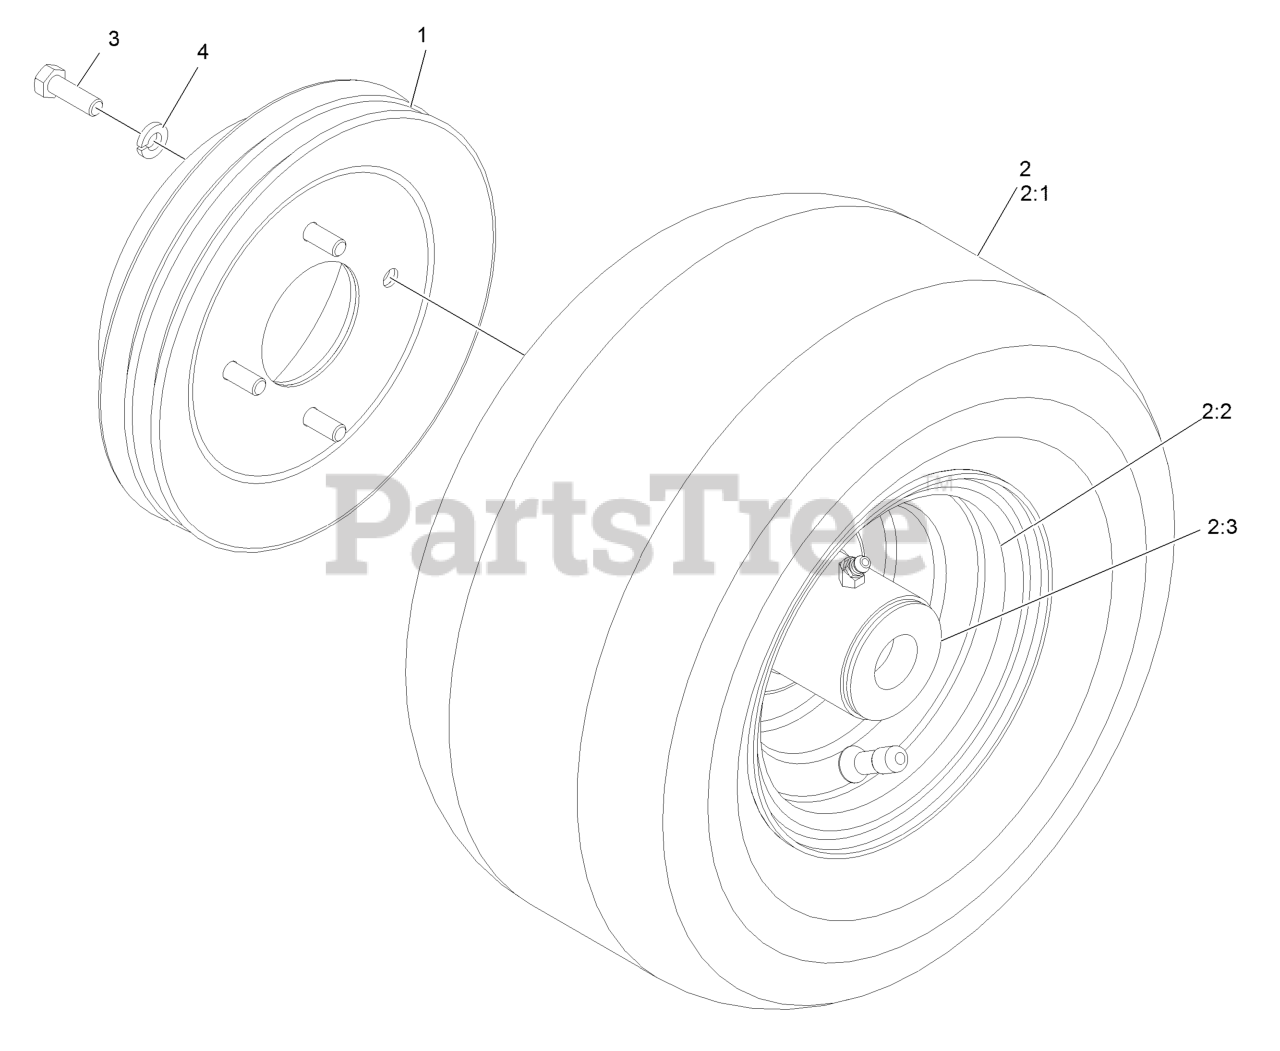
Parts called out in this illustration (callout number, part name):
1	Drum And Sheave ASM
2	Wheel And Tire ASM
2:1	Tire
2:2	Wheel And Hub ASM
2:3	Bearing-Flanged
3	Screw-HH 5/16-18 X 1
4	Washer-Lock 5/16 Heavy
